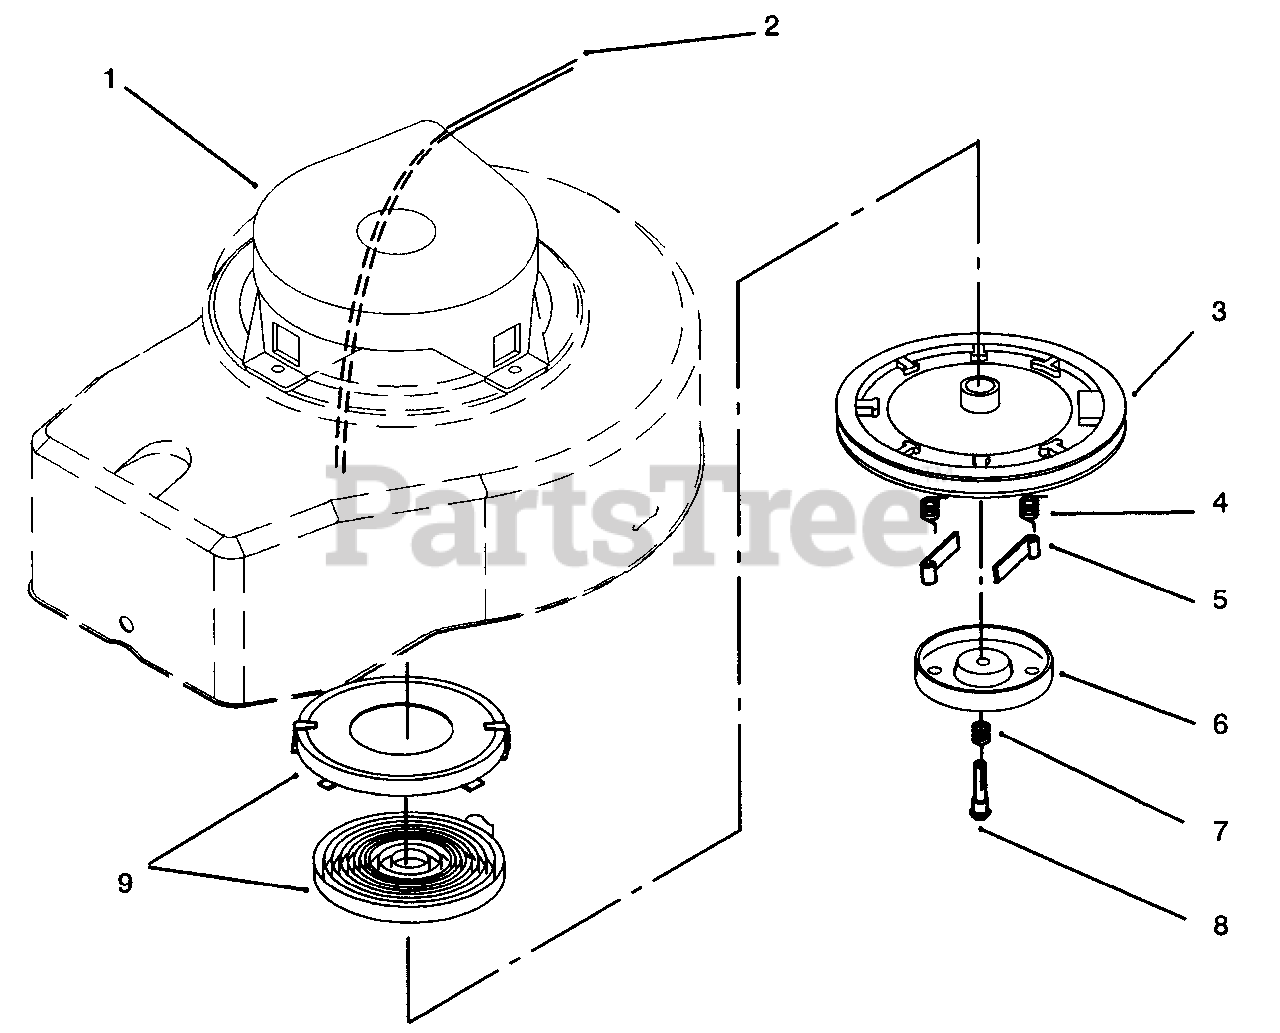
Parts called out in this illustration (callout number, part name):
1	Housing-Recoil
2	Rope-Starter
3	Pulley Assembly
4	Spring-Dog
6	Retainer
9	Spring Keeper Assembly
